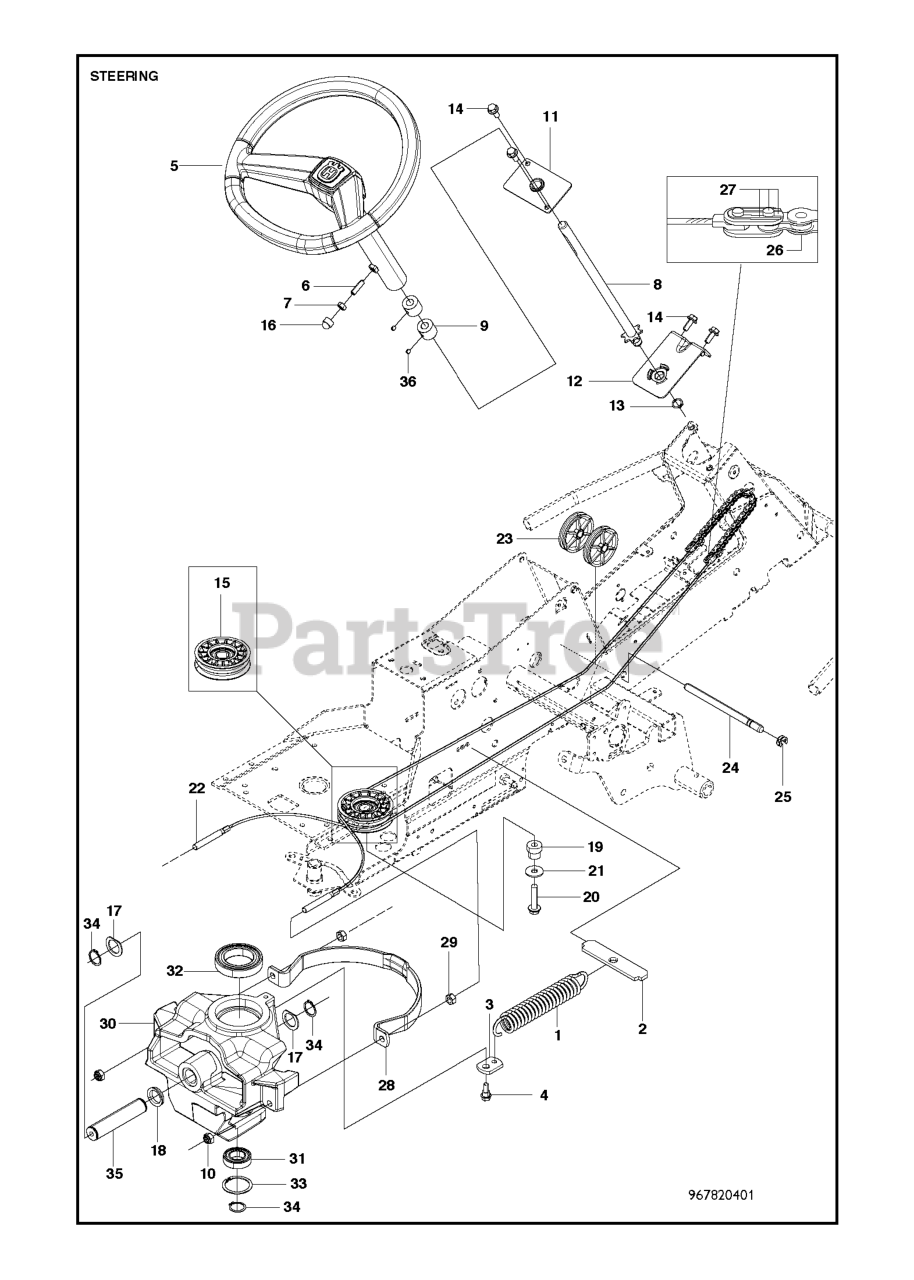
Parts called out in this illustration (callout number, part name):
2	SPRING BRACKET
5	STEERING WHEEL
7	NUT
9	SPACER
10	NUT
11	BRACKET STEERING ASSY WITH BUS
12	BRACKET STEERING ROD ASSY
13	RETAINING RING SGA 15
16	PROTECTIVE COVER
20	COLLAR SCREW
22	WIRE ASSY
25	RETAINING RING
26	STEERING CHAIN
28	WIRE GUIDE
31	Ball Bearing 6005-2rs
32	BALL BEARING 6010 2RS1
33	CIRCLIP SGH 47
34	RETAINING RING SGA 25
